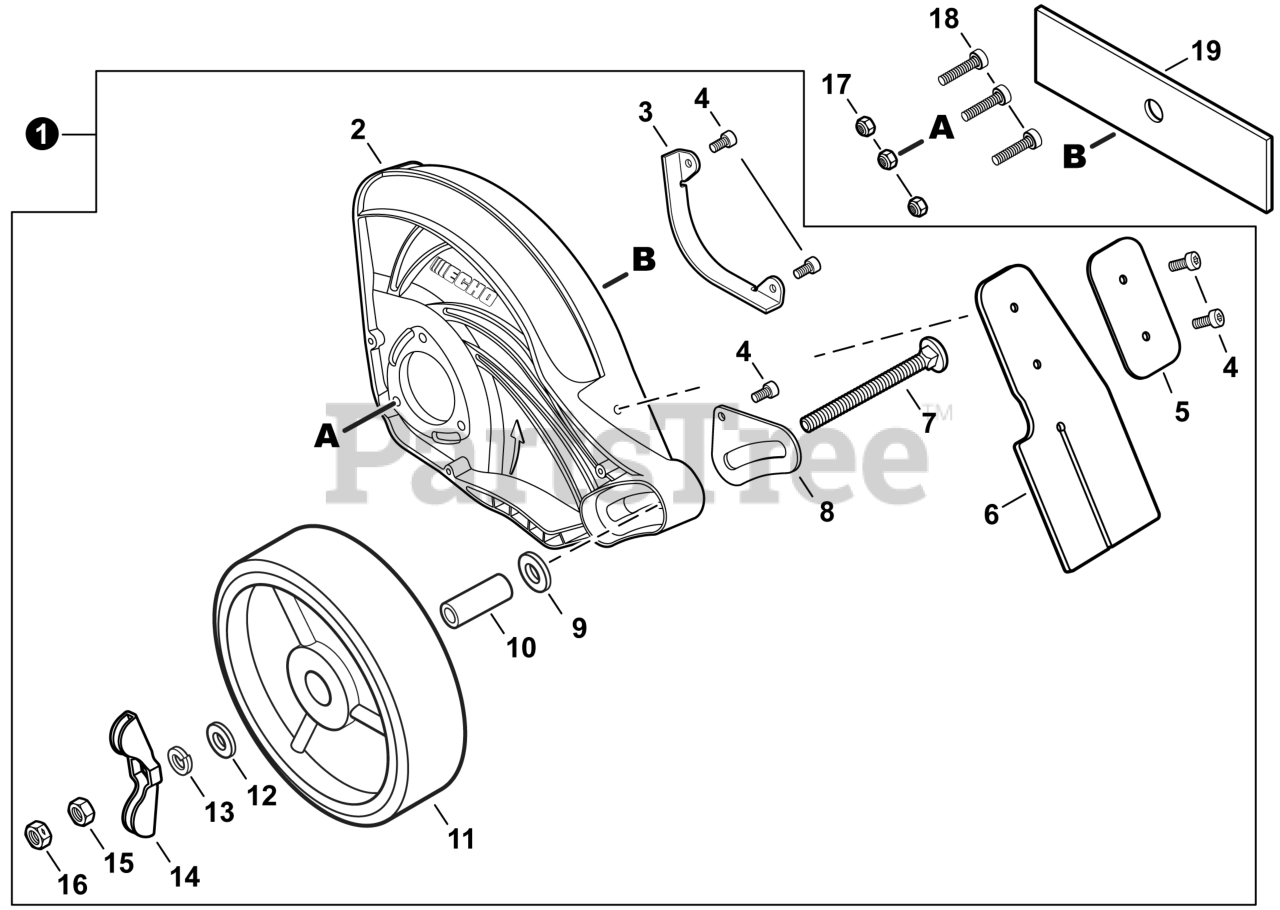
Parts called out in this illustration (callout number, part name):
1	SHIELD KIT, EDGER - PLASTIC
2	SHIELD, BLADE
3	GUARD, SHIELD
4	BOLT, TORX 4x12
5	PLATE, FLAP
6	FLAP, DEBRIS
7	BOLT M8-1.25x80 MM
8	BRACKET, WHEEL
9	WASHER M10
10	COLLAR 12
12	WASHER 8
13	WASHER, SPRING 8
14	KNOB, FASTENER
16	NUT, LOCK M8
17	NUT, LOCK M5
18	BOLT, TORX 5x25
19	BLADE - 2 PK
